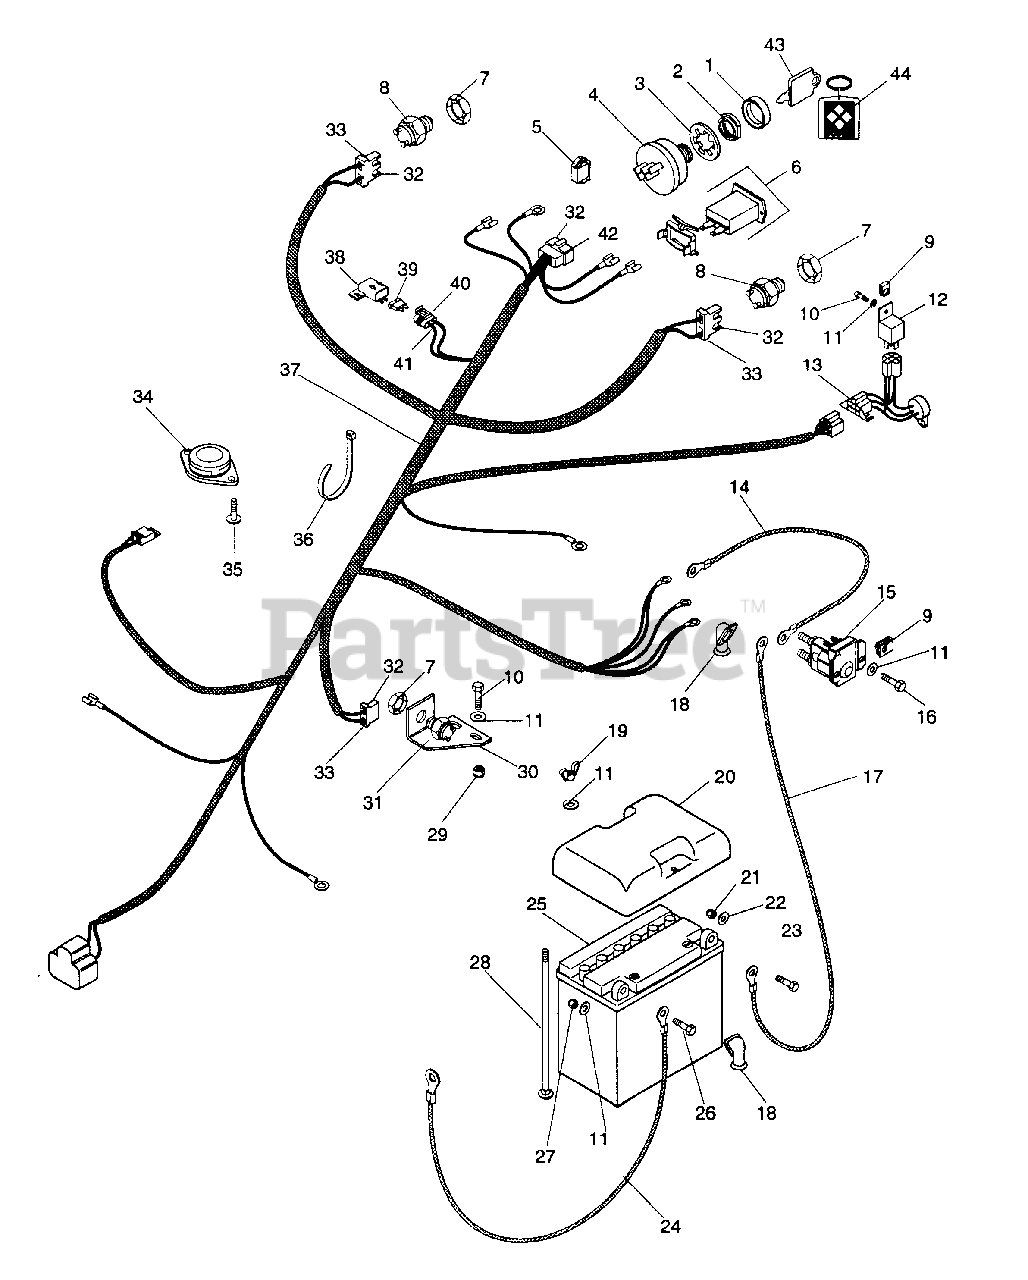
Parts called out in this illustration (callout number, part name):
1	Cap, Igntion Switch
2	Nut, Panel .562-24 Greco
3	Washer, Lock Internal .563 x .040
4	Ignition Switch (02,04)
4	Switch, Ignition W/Ground (01,03)
5	Light, Indicator
6	Hour Meter
7	Nut, Stamped 9/16-18
8	Switch-Neutral Start N.O.
9	Nut, Speed .25-20
10	Bolt-Hex .25020 x .63
11	Washer, Flat Steel .281 x .62 x .065
12	Relay
13	Module, Time Delay
14	Cable, Solenoid to Starter (02,04)
14	Cable, Starter (01,03)
15	Solenoid
16	Bolt-Hex .25-20 x .63
17	Cable, Battery to Solenoid
18	Battery Cable Insulator
19	Nut-Wing .250-20
20	Cover-Battery
21	Nut-Lock-Nylon .312-19 PL
22	Washer-Flat-Steel .344 x .688 x .065 PL
23	Bolt-Hex .31-18 x 1.00 Pl Gr 5
24	Cable, Negative Battery
25	12 Volt Battery
26	Bolt-Hex .25-20 x .75 Pl Gr. 5
27	Nut-Lock Nylon .250-20 Pl
28	Bolt-Carriage .25-20 x 7.00
29	Nut-Lock-Nylon .250-20 Pl
30	Bracket, Interlock Switch
31	Switch
32	Terminal
33	Connection, 2-Wire Switch
34	Seat Switch
35	Screw, Machine .25-20 x .50
36	Tie Wrap, Black
37	Harness, Wiring 18 Hp Kohler (02,04)
37	Harness, Wiring 16 Hp B&S (01,03)
38	Cover
39	Fuse, 25 AMP
40	Assembly, Connection Weather Tight
41	Terminal, 10-12 Gage Wire
42	Connector
43	Ignition Switch Key
44	Key Chain
